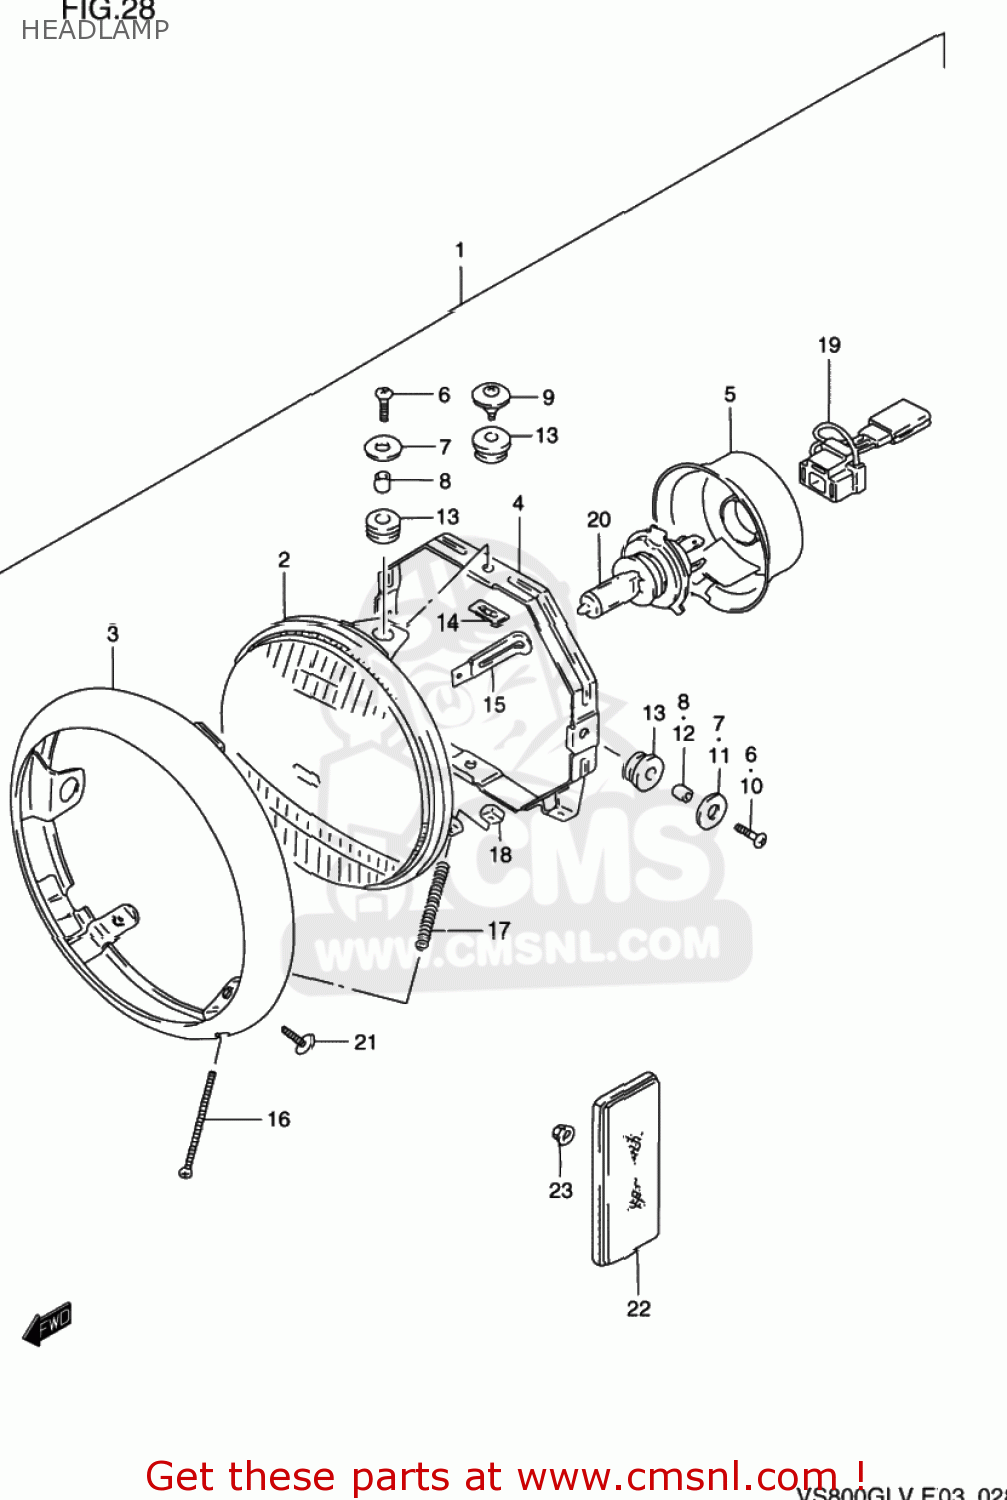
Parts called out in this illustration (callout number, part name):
1	HEADLAMP ASSY
2	UNIT,LAMP
3	RIM
4	RING,MOUNTING
5	COVER,SOCKET
6	SCREW(5X14)
7	WASHER
8	SPACER
9	SCREW,MOUNTING
10	SCREW(5X14)
11	WASHER (5.5X18X1)
12	SPACER
13	CUSHION
14	NUT
15	CLAMP(L:45)
16	SCREW,HEADLAMP ADJUST
17	SPRING
18	NUT
19	SOCKET
20	BULB(12V60/55W,H4)
21	SCREW
22	REFLEX REFLECTOR,FR SIDE
23	NUT
